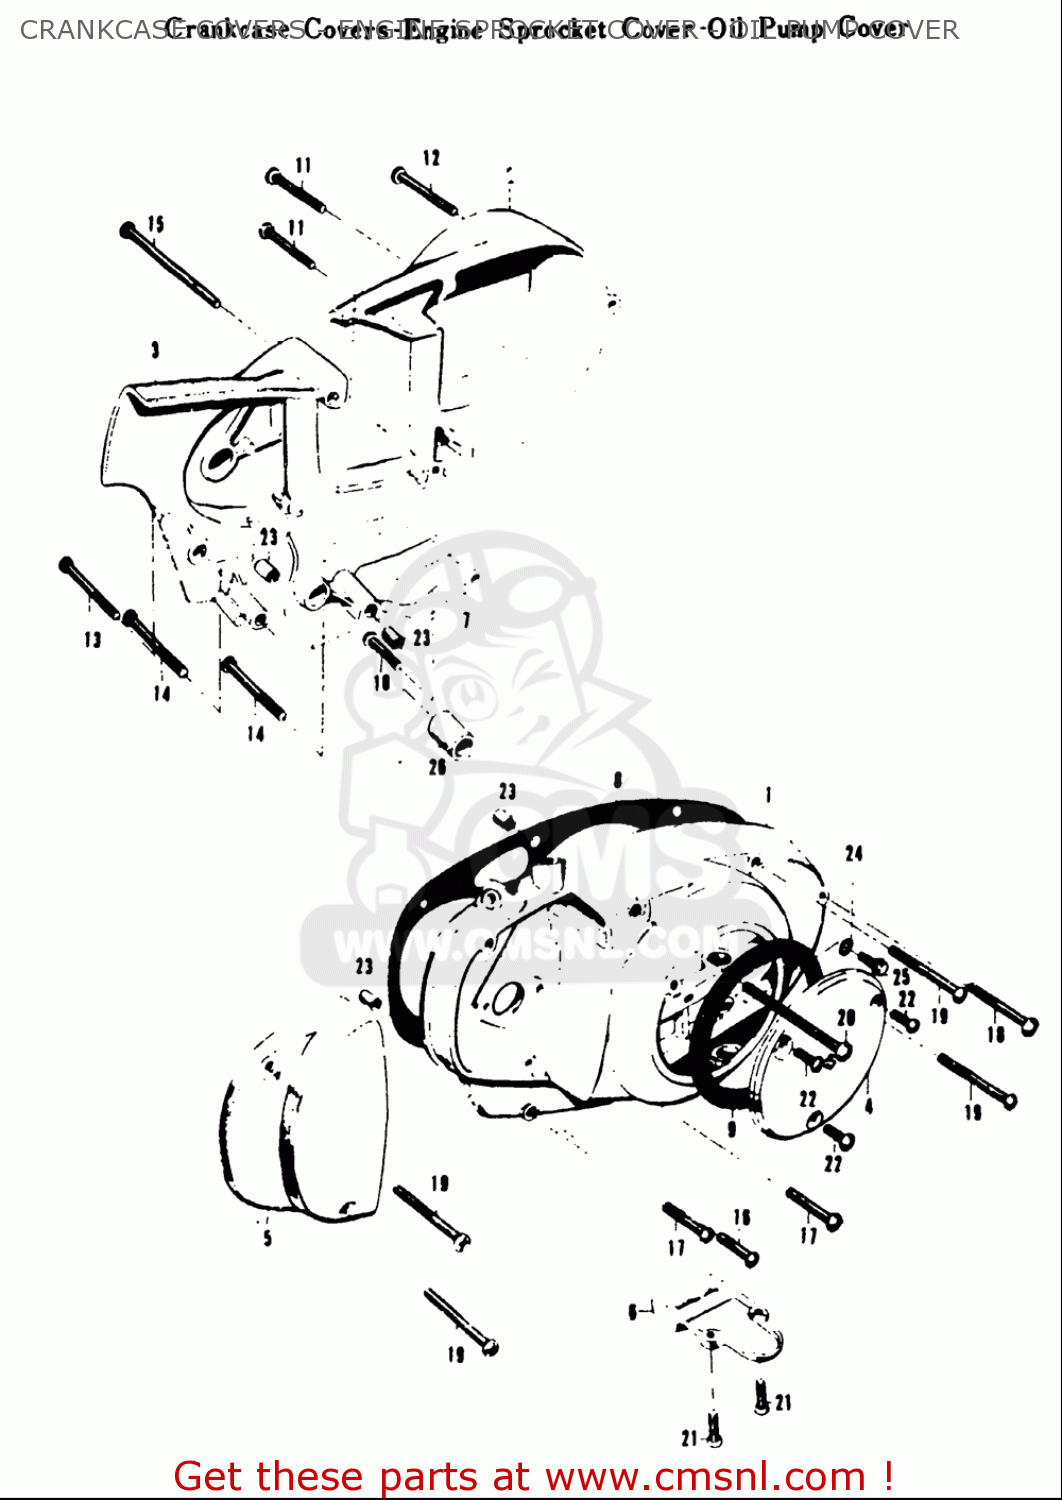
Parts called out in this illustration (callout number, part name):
8	CRANKEASE RIGHT COVER GASKET
9	CLUTCH RELEASE ADJUSTING CAP G (TC250; I.D.=78(3.07). O.D.=110(4
16	SCREW
17	SCREW
18	SCREW
19	SCREW
20	SCREW
22	SCREW
23	PIN
24	GASKET(6.2X11X1) (NAS)
